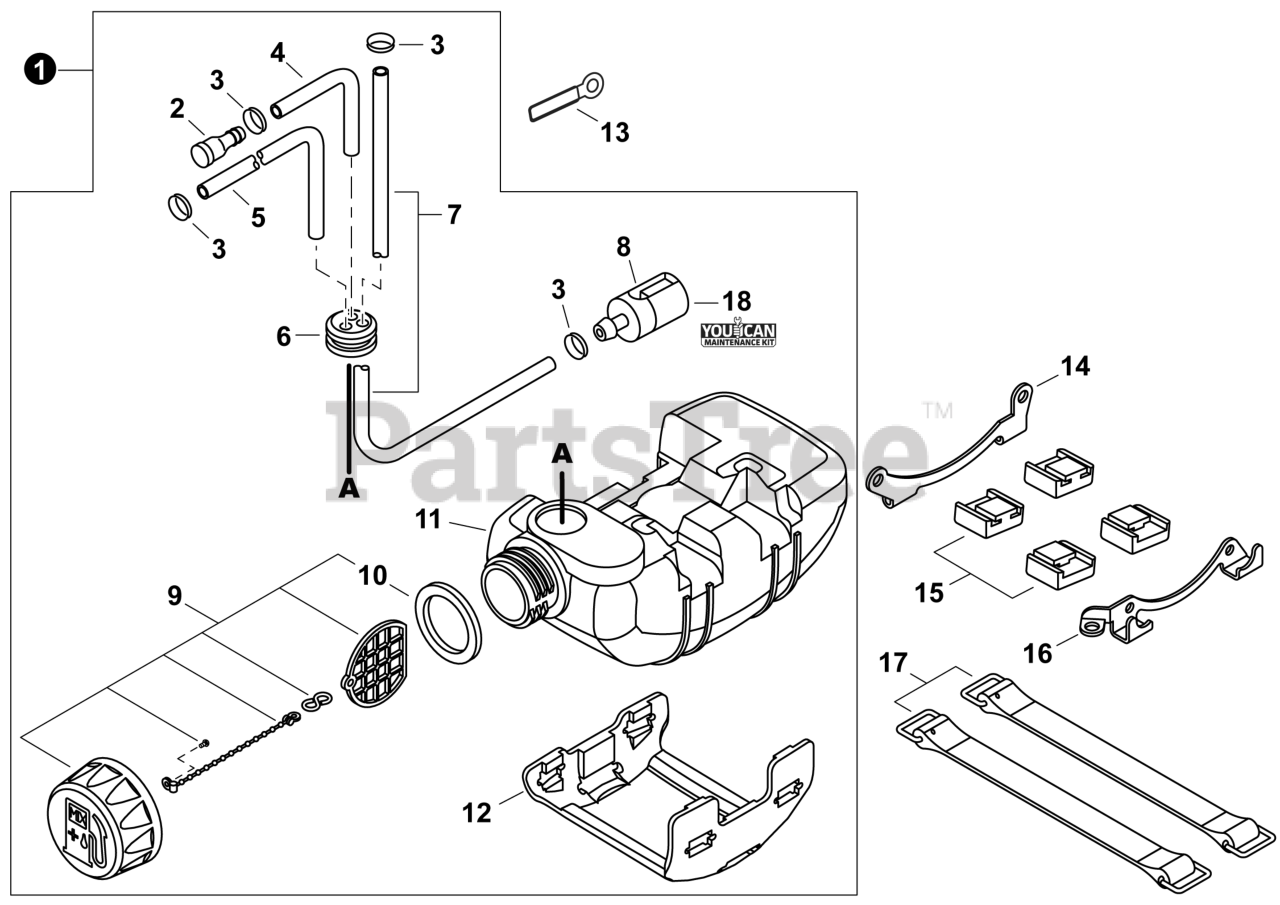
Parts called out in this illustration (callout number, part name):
1	TANK ASSY, FUEL
2	VENT ASSY
3	CLIP Ø6
4	PIPE 3×6×90 MM
5	PIPE, FUEL 3×6×50
6	GROMMET, FUEL
7	PIPE, FUEL
8	FILTER, FUEL
9	CAP ASSY, FUEL
10	GASKET, FUEL CAP
11	TANK, FUEL
12	GUARD, FUEL TANK
14	BRACKET M
15	CUSHION, FUEL TANK
16	BRACKET S
17	STRAP, FUEL TANK
18	TUNE-UP KIT - YOUCANT
